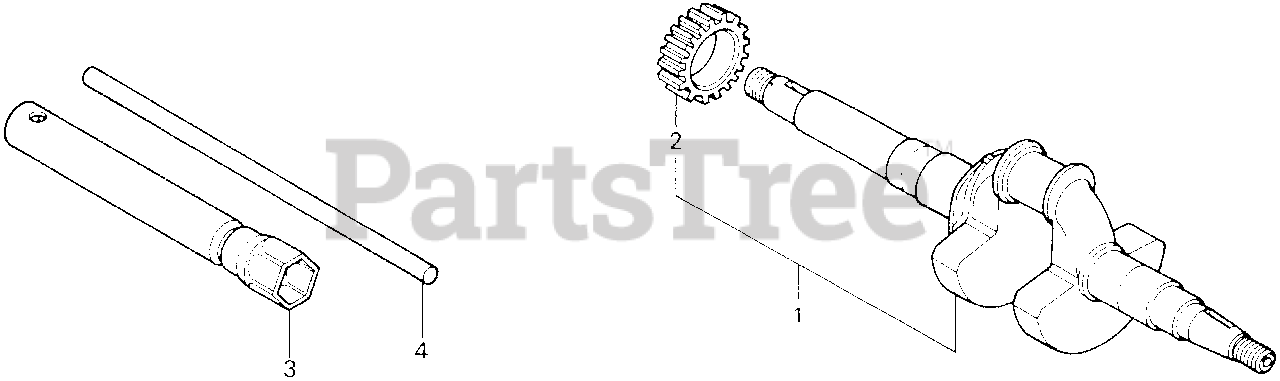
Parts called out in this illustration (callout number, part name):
1	CRANKSHAFT (U-TYPE)
2	GEAR, TIMING
3	WRENCH, SPARK PLUG (NOT AVAILABLE)
4	HANDLE, BOX WRENCH
